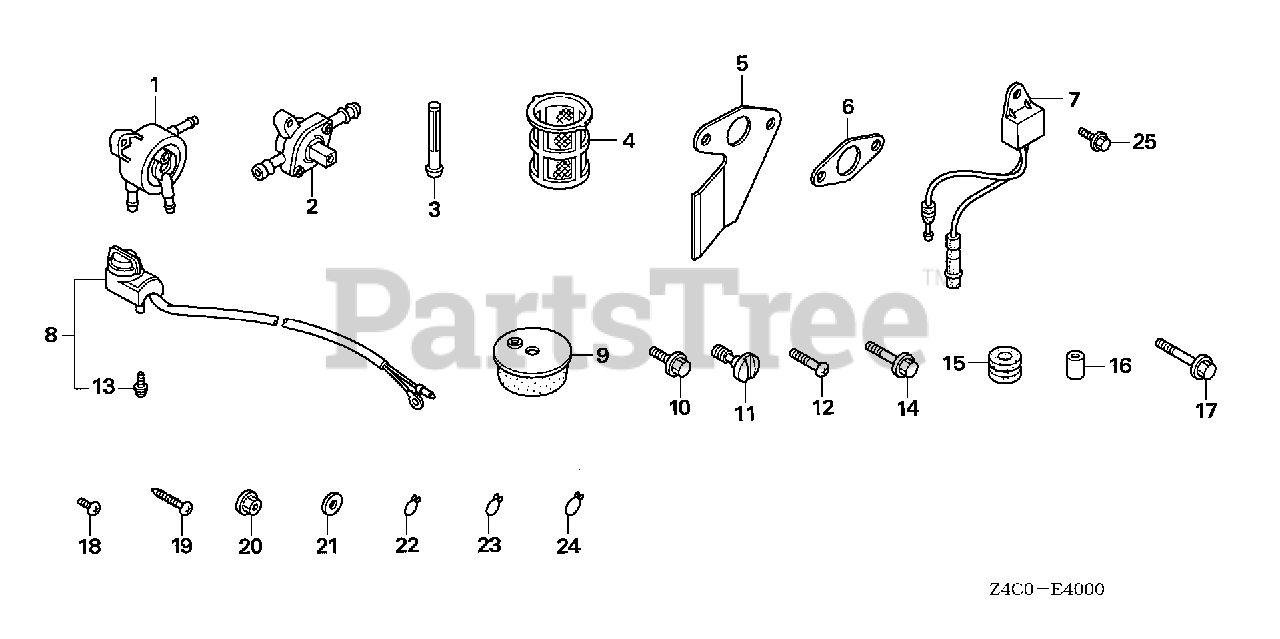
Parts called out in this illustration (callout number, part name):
1	PUMP ASSY., FUEL
2	PETCOCK ASSY.
3	FILTER, FUEL
4	FILTER, FUEL
5	GASKET, EX. PIPE
6	GASKET, MUFFLER
9	RUBBER (LOWER)
10	BOLT, FLANGE (6X12) (CT200)
11	BOLT, AIR CLEANER COVER (- SCREW)
12	SCREW, PAN (4X19)
14	BOLT, FLANGE (5X20)
15	RUBBER, CONTROL BOX
16	COLLAR, CONTROL BOX
17	BOLT-WASHER (6X25)
19	SCREW, TAPPING (5X20) (PO)
20	NUT, FLANGE (5MM)
21	WASHER, PLAIN (6MM)
22	CLIP, TUBE (B8)
23	CLIP, TUBE (B10)
24	CLIP, TUBE (C11)
